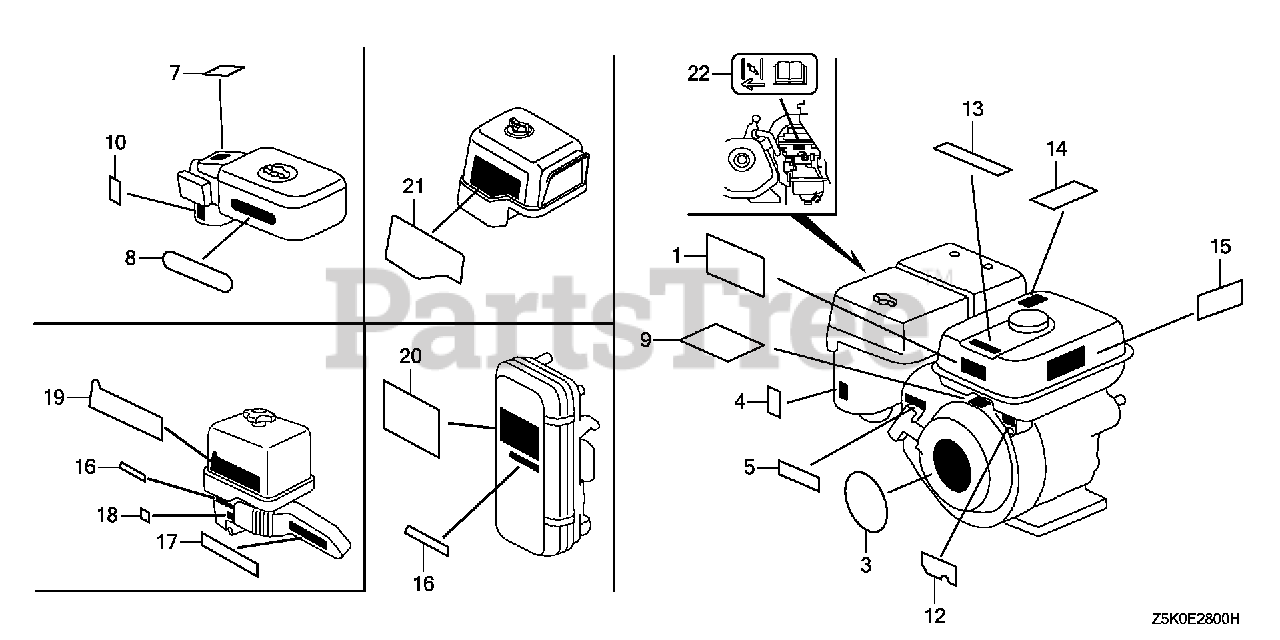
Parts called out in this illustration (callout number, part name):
14	MARK, EX. CAUTION (ENGLISH)
15	MARK, OPERATOR CAUTION (ENGLISH)(MADE IN THAI)
16	MARK, CHOKE
17	MARK, HONDA
18	MARK, FUEL
19	MARK, SALES POINT
22	MARK, CHOKE
